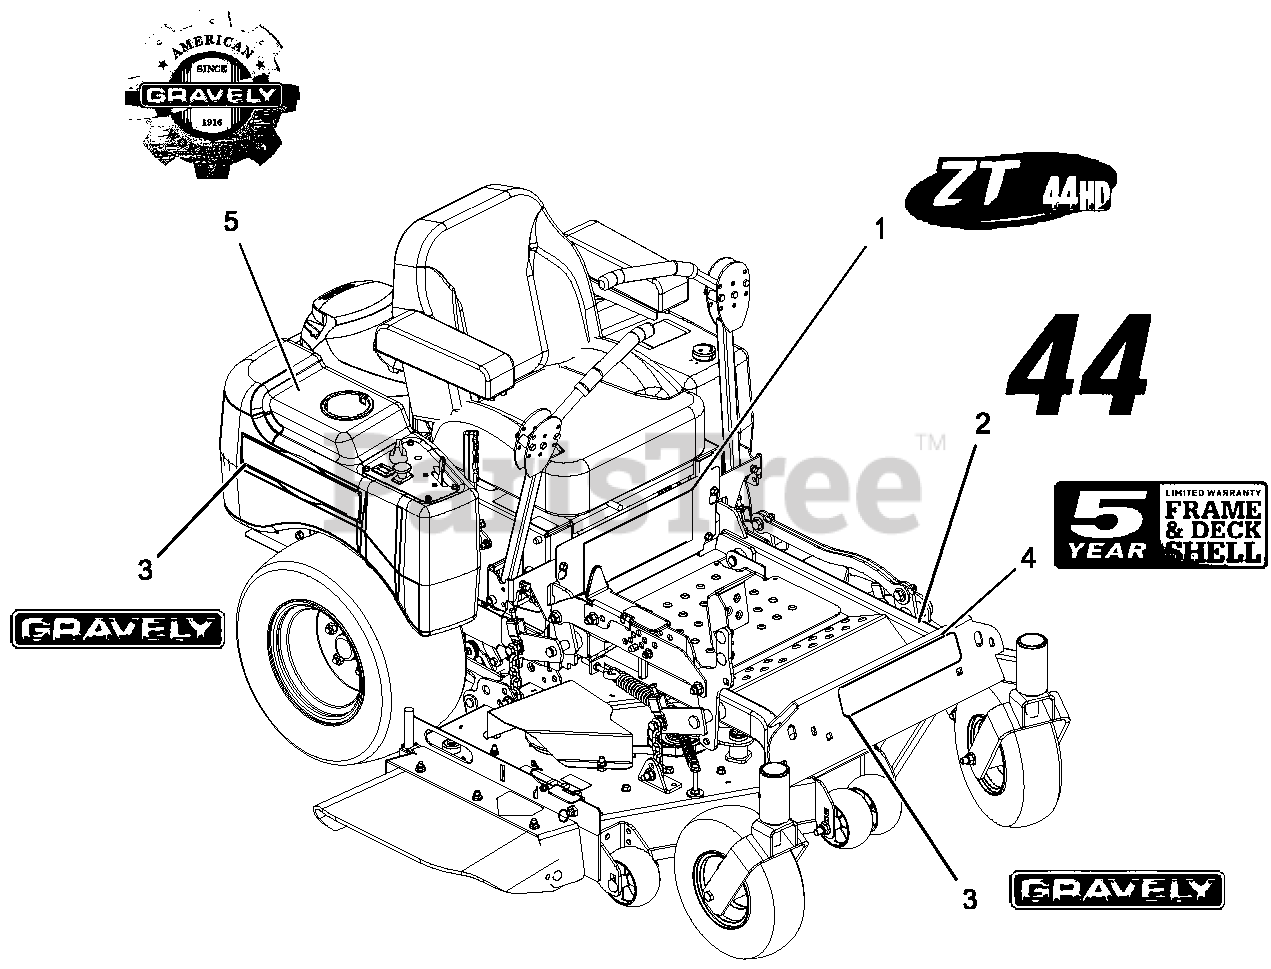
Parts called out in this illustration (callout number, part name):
1	DECAL, 44HD
2	DECAL, 44''
3	DECAL, FUEL TANK-GRAVELY
4	DECAL, DECK WARRANTY-FAB GRAVELY
5	DECAL, GRAVELY HERITAGE-SMALL
